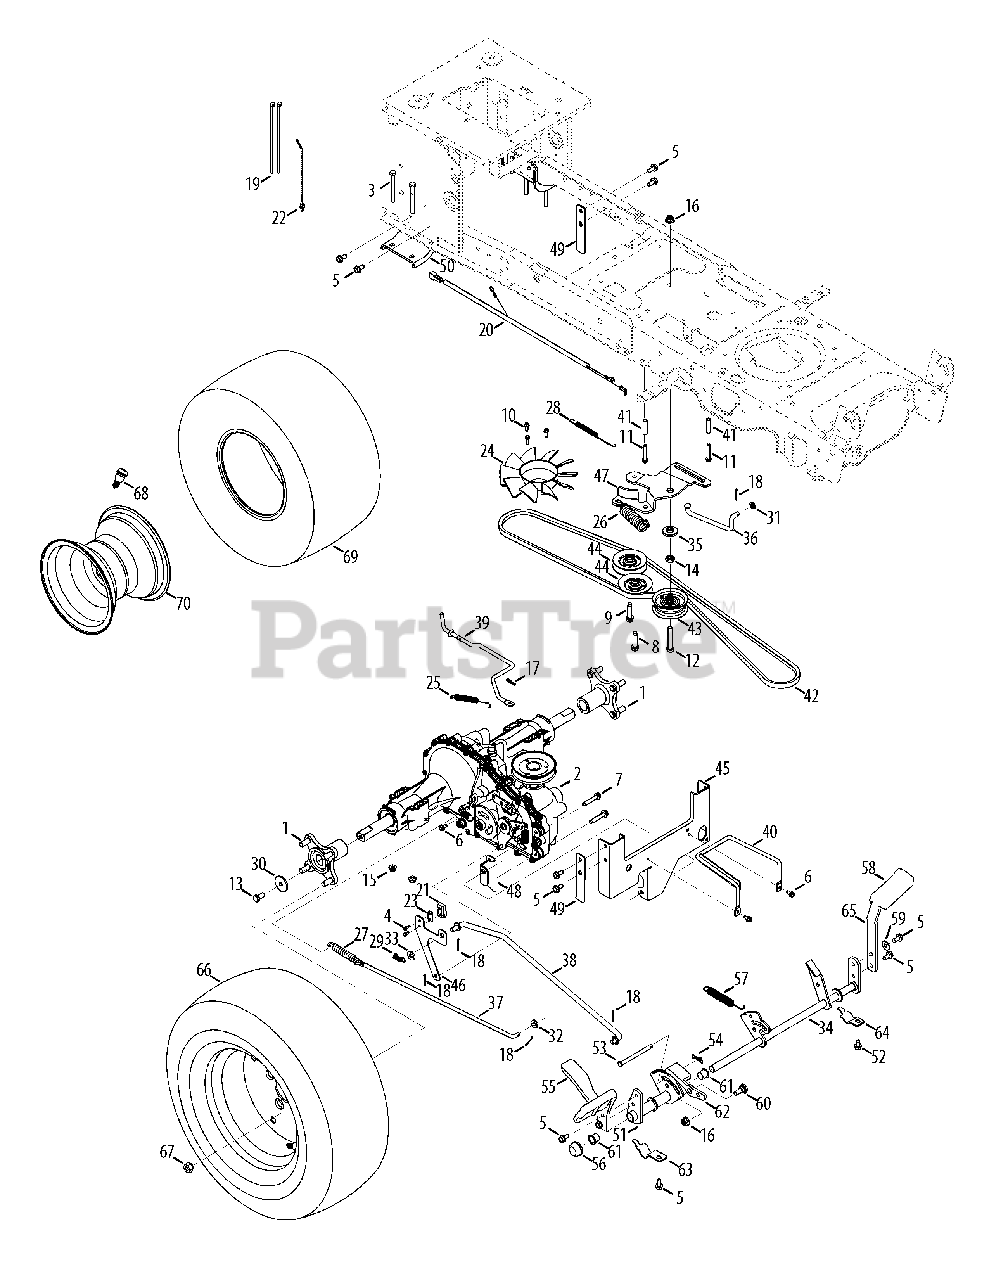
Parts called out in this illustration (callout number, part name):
1	Wheel Hub
2	Transmission
3	Hex Screw 5/16-18 X 3.00
4	Hex Wash HD AB S-Tapp Screw #8-.50
5	Hex Wash Hd. Tapp Screw. 5/16-18 x .75
6	Hex Wash S-Tapp Screw 1/4-20 x .50
7	Hex Wash TT-Tap Screw 5/16-18 x 1.75 Lg.
8	Hex L-Wash HD Screw 3/8-16 x 1.5
9	Hex L-Wash TT Screw. 3/8-16 x 1.88
10	Screw, #12-24 x .625
11	Hex Washer Hd. TT Screw 1/4-20 x 1.625
12	Hex Bolt 3/8-16 x 2.25" Lg.
13	Hex Cap Lock Screw 3/8-16 x .75 Gr. 5
14	Hex Jam Nut 7/16-20
15	Flange Locknut 5/16-18 Gr. F, Nylon
16	Flange Locknut 3/8-16 Gr. F Nylon
17	Int. Cotter Pin .072 x 1.13" Lg.
18	Cotter Pin 3/32 dia x 1.00 Lg.
19	Cable Tie
20	Jumper Harness
21	Short Spring Switch
22	Push Mount Tie
23	Insulator Nut Plate
25	Extension Spring .50 dia. x 5.0" Lg.
26	Extension Spring 1.0 dia. x 4.75" lg.
27	Extension Spring .59 dia. x 4.0" Lg.
28	Extension Spring .38 dia. x 5.6" Lg.
29	Extension Spring 3/8 dia. x 1.44" Lg.
30	Flat Washer .39 ID x 1.5 OD x .135
31	Flat Washer .344 ID x .625 OD x .063
32	Flat Washer .312 ID x .75 OD
33	Flat Washer .406 ID x .812 OD x .134
34	Brake Control Ass’y
35	Shoulder Spacer 1.375 x .380 x .183
36	Footpedal By pass Rod
37	Brake Rod
38	Control Rod
39	Disengage Rod
40	Belt Keeper
41	Spacer .260 x .372 x 1.420
42	V-Belt, 4L x 77.0
43	Idler Pulley, Flat 2.75 OD
44	Idler Pulley V-Type x 3.06
45	Torque Bracket
46	Switch Bracket
47	Idler Bracket (Centre Double)
48	Deck Bracket
49	Plate Bracket
50	Axle Bracket
51	Grill Pivot Bracket
52	Self-tap ping Screw 5/16-18 x .625
53	Clevis Pin 5/16 x 3.985
54	Bow-Tie Cotter Pin
55	Control Pedal
56	Push Cap 5/8" Dia Rod
57	Extension Spring .63 dia. x 4.95
58	Brake Pedal Pad
59	Cupped Washer .345 ID x .88 OD x .060
60	Shoulder Screw .500 x .25
61	Nyliner Flanged Brg.
62	Cruise Latch
63	Pedal Strap Support Bracket
64	Pedal Strap Support Bracket
65	Brake Pedal Bracket
66	Wheel Ass’y
67	Lub Nut, 7/16-14
68	Air Valve
70	Rim Assembly
